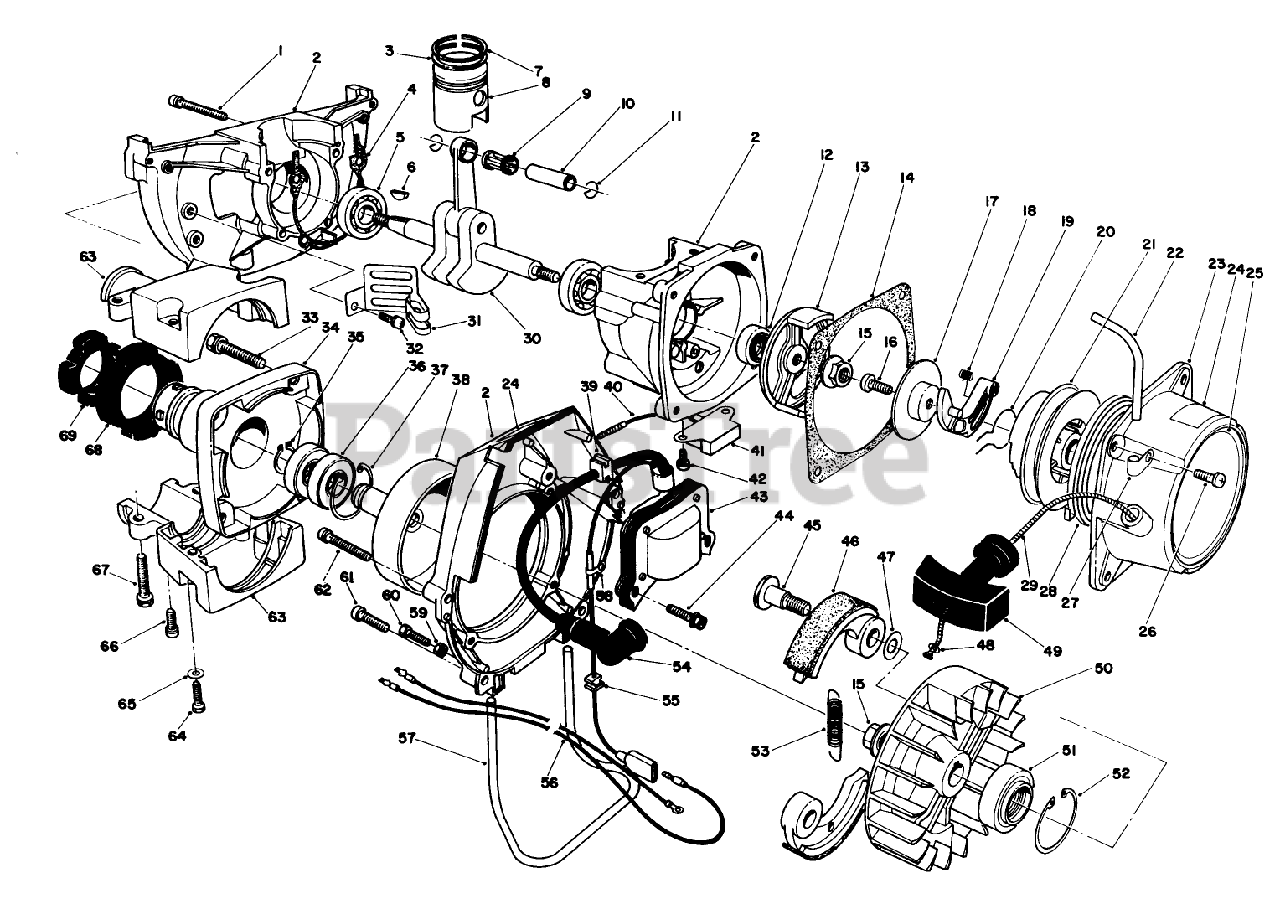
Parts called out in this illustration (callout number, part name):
1	SCREW & WASHER
3	RING,PISTON
5	BALL BEARING
7	RING,PISTON
8	PISTON SET
9	BEARING, NEEDLE
12	OIL SEAL
18	SPRING, RETURN
19	RATCHET
23	RECOIL STARTER
28	SPRING, SPIRAL
36	BALL BEARING
38	DRUM, CLUTCH
41	UNIT, TRANSISTOR
43	COIL, IGNITION
44	BOLT AND WASHER
47	WASHER
51	OIL SEAL
53	SPRING
54	CAP-PLUG
57	TANK GUARD
68	RUBBER, CUSHION (A)
69	RUBBER, CUSHION (B)
